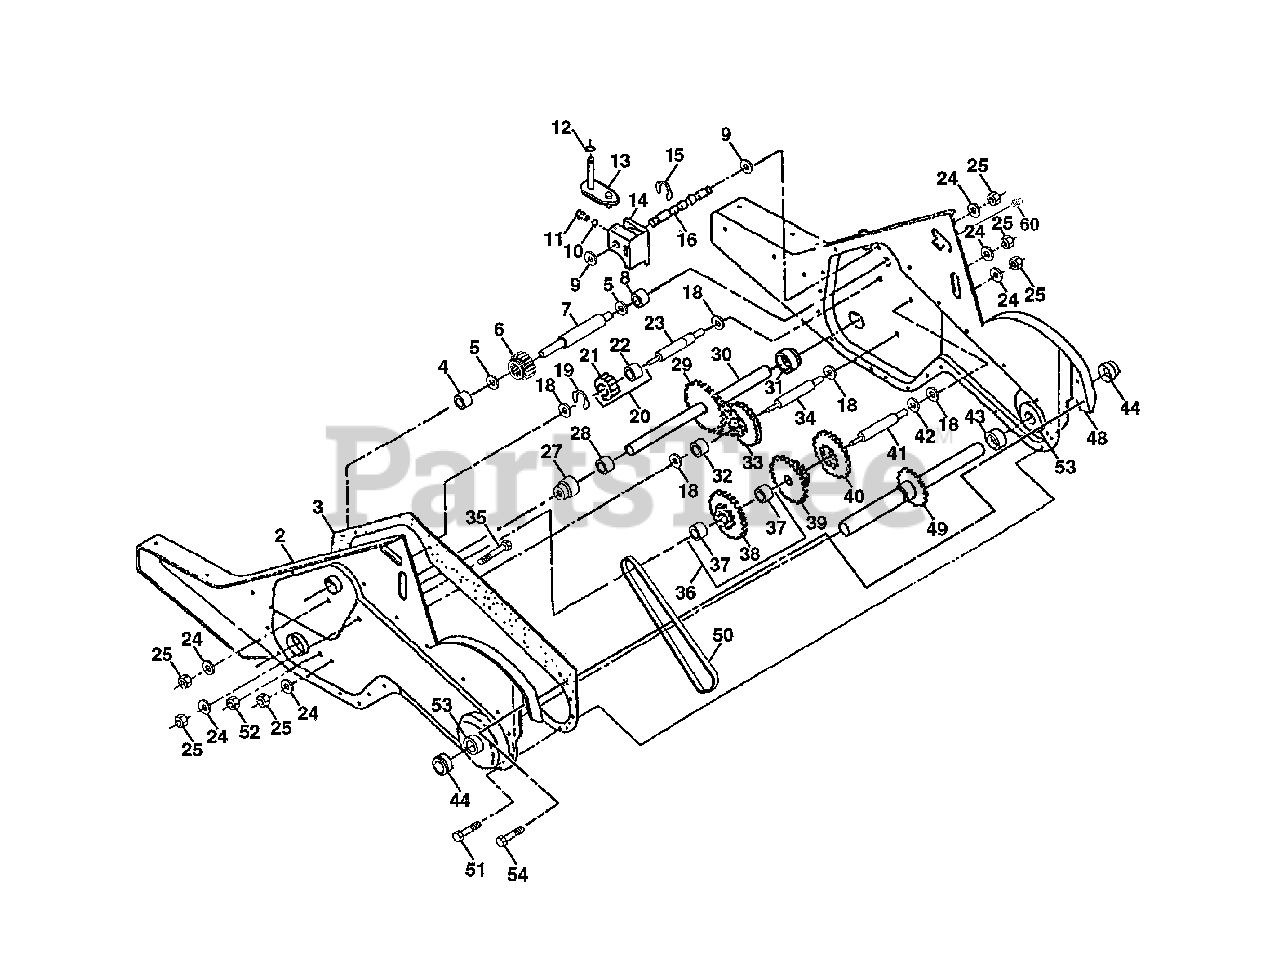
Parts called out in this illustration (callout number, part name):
1	Transmission Assembly
2	Gearcase, L.H. w/Bearing
3	Gasket, Gearcase
4	Bearing, Needle
5	Washer, Thrust 5/8 x 1.10 x 1/32
6	Pinion, Input
7	Shaft, Input
8	Bearing, Needle
9	Washer, Seal
10	Ball, Steel
11	Spring, Shift, Fork
12	O-Ring
13	Arm, Shift
14	Fork, Shift
15	Ring, Klip
16	Shaft, Shift
18	Washer
19	Ring, Klip
20	Gear, Assembly, Reverse Idler
21	Gear, Reverse Idler
22	Bearing, Needle
23	Shaft, Reverse Idler
24	Washer, Lock 7/16
25	Nut, Hex 7/16-20
27	Bearing, Shaft, Ground Drive L.H.
28	Spacer 0.765 x 1.125 x 1.23
29	Chain #35-50 Pitch
30	Ground Shaft Assembly
31	Bearing, Shaft, Ground Drive R.H.
32	Spacer 0.70 x 1.00 x 1.150
33	Sprocket and Gear Assembly
34	Shaft, Reduction (2nd)
35	Screw, Whiz, Lock 5/16-18 x 3-1/2
36	Sprocket Assembly w/Bearing
37	Bearing, Needle
38	Sprocket, Tine
39	Gear, Cluster, Red 1st & 2nd
40	Gear, Reverse
41	Shaft, Reduction (1st)
42	Washer, Thrust
43	Spacer 1.01 x 1.75 x 0.760
44	Seal Asm. Oil
48	Gearcase, R.H. w/Bearing
49	Shaft, Tine
50	Chain, Roller #50-50 Pitch
51	Screw 1/4-20 x 1/2
52	Nut, Hex 5/16-18
53	Kit, Bearing
54	Screw 1/4-20 x 3/4
60	Grease Fitting
60	Grease, Plastilube #1
